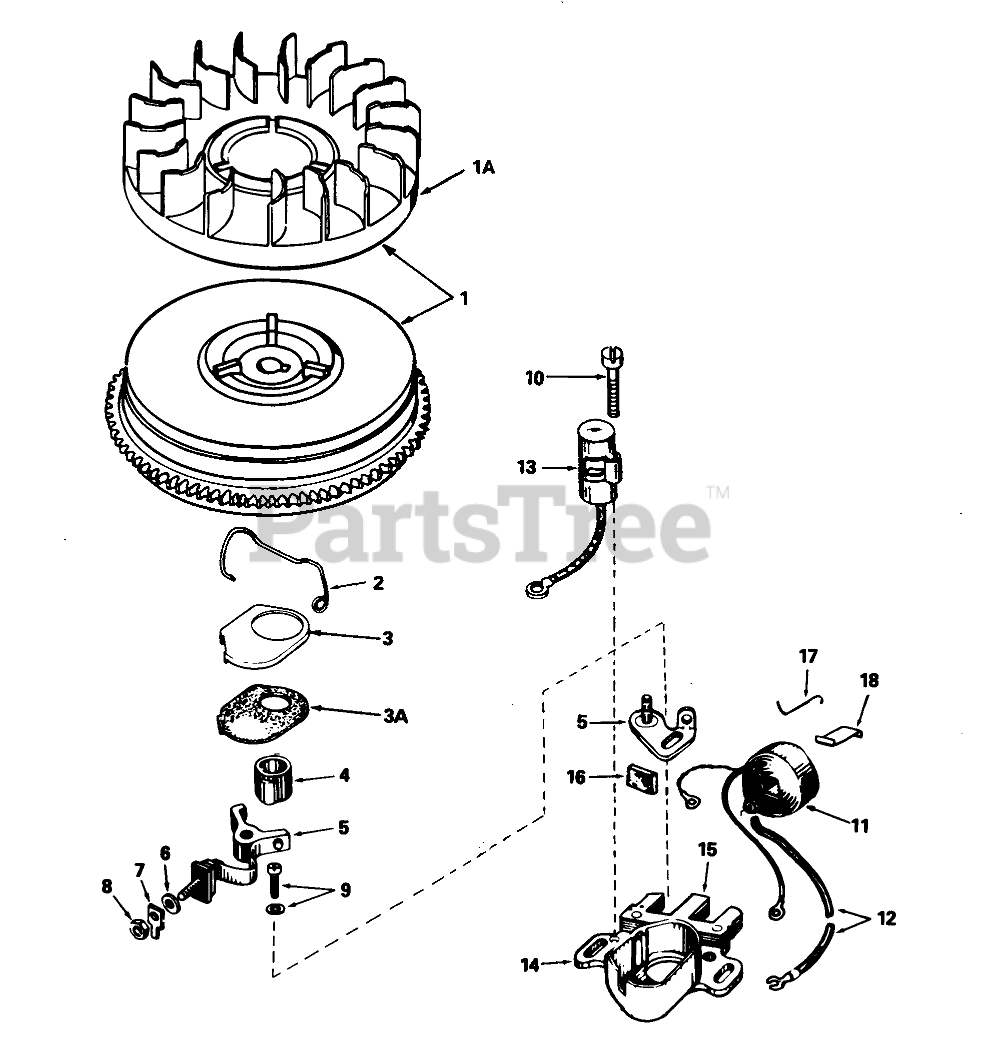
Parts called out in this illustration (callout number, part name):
1	Flywheel (Incl. Ref. #1A, 3 & 3A)
1A	Fan
2	Spring Breaker Box
3	Cover-Dust
3A	Gasket, Dust Cover
4	Cam-Breaker
5	Breaker Assy.
6	Washer
7	Terminal, Ground
8	DECAL
9	Breaker Screw
10	Condenser Screw
11	Coil Assembly (Incl. Ref. #12)
12	Wire, Lead
13	Condenser
14	Core & Plate
15	Stator Assembly (Incl. Ref. #2, 3, 3A, 5-14 & 16-18)
16	Felt,Cam Wiper
17	Clip, Coil
18	Spring Coil Wedge
